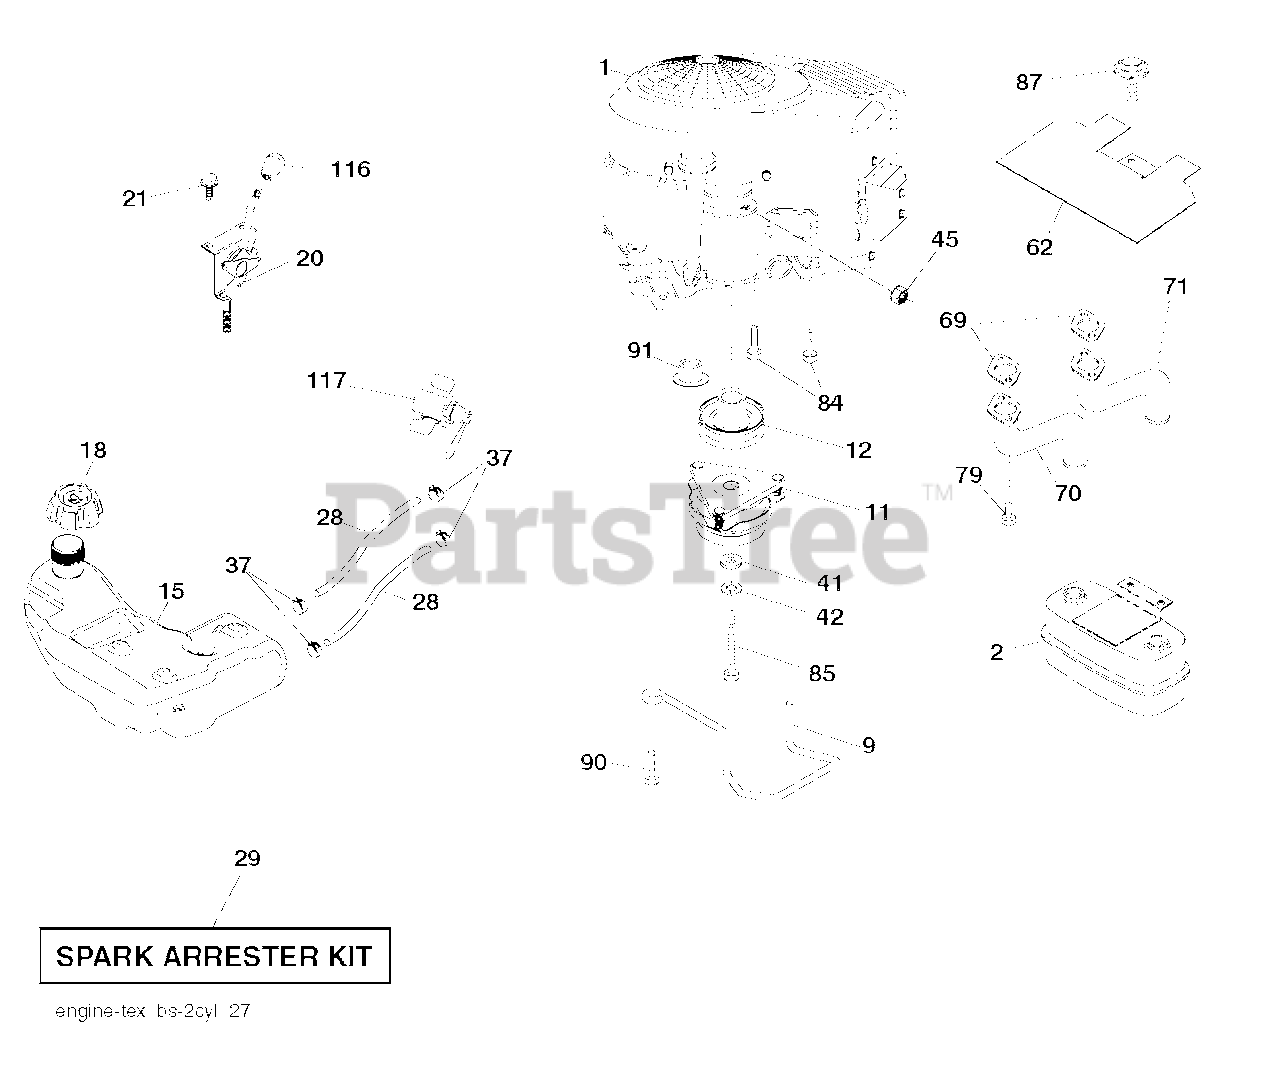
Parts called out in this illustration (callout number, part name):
2	MUFFLER.ASM.TWN.EXTNDED.DFLCTR
9	KEEPER.BELT.ENGINE.4.2
11	CLUTCH.ELECTRIC.LT.48"*
12	PULLEY.ENGINE.TUFFTORQ
18	CAP.FL.R.3'N/CARB.H.CROWN.498
20	CONTROL THROTTLE/CHOKE
21	SCREW.#10 X 0.750.BOS
28	REPL BY 532 00 85-43
29	KIT.SPARK ARRESTOR 794945 B&S
37	HOSE CLAMP
42	LOCKWASHER
45	NUT
62	SHIELD.HEAT.MUFFLER
69	GASKET.MUFFLER
70	RP.EXHAUST.TUBE.LH.BS/TWIN
71	EXHAUST.TUBE.RH.BS/TWIN
79	SCREW.SOCKET.HEAD.5/16-18
84	SCREW.3/8-16
85	BOLT HEX 7/16-20X4-1/4"
87	Bolt, 5/16-18 X 1-3/4
90	SCREW 3/8-16X1
91	BUSHING.1.375OD
116	KNOB - SHIFT
117	VALVE FUEL RESERVE
